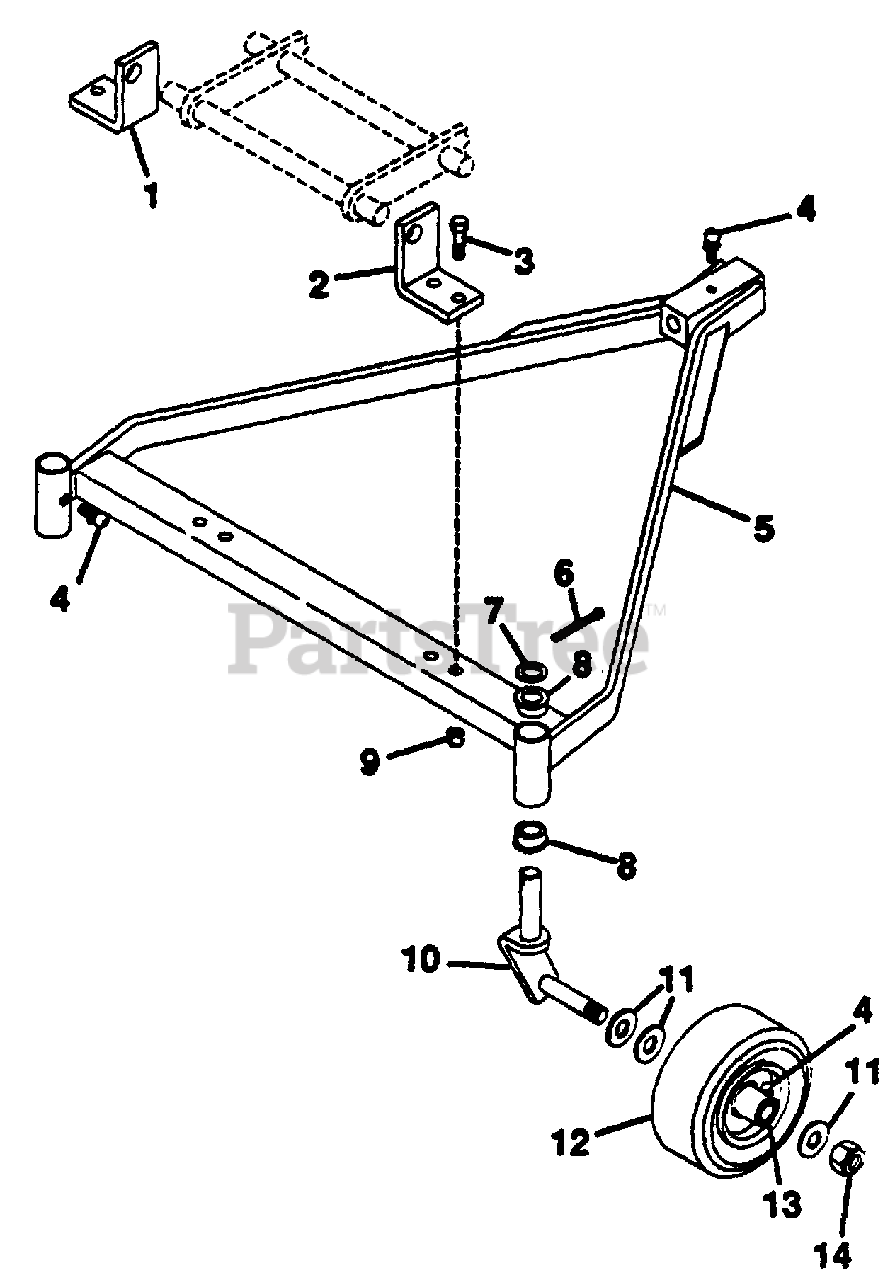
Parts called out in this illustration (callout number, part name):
1	Support, Pivot Arm R.H.
2	Support, Pivot Arm L.H.
3	Bolt, Hex 3/8-16x1.25
4	Fitting, Lube 1/4-28
5	Weldment, Frame
6	Pin, Cotter .187x1.625
7	Race, Bearing Thrust
8	Bushing, Pivot
9	Nut, Lock 3/8-16
10	Weldment, Caster Fork
11	Washer, Flat .812x1.496x.134
12	Wheel, Gauge
13	Bearing, Gauge Wheel
14	Nut, Lock 3/4-10
